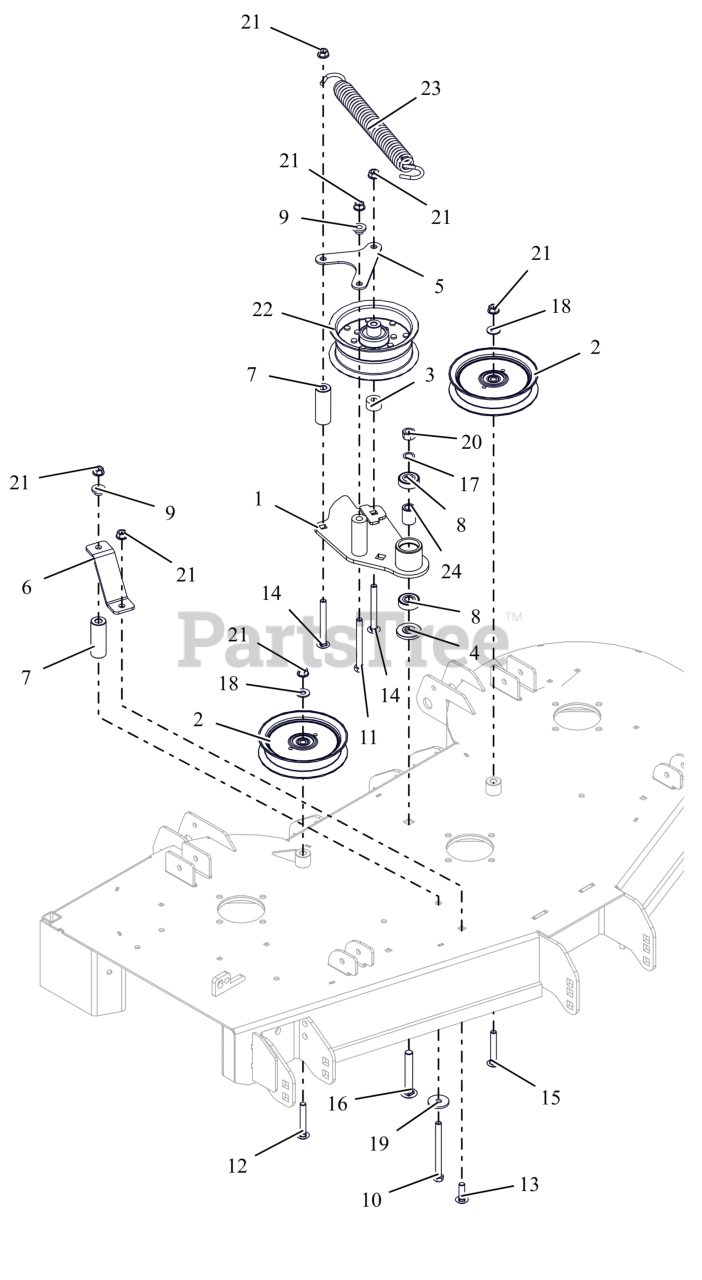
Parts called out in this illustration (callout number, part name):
1	WLDMT, IDLER ARM
2	IDLER, FLAT 5.00"
3	SPACER .390X1.000X.562
4	SPACER, IDLER ARM
5	BRKT, SUPPORT (BLACK)
6	BRKT, SPRG ANCHOR (BLACK)
7	SPCR, TUBE (BLACK)
8	BRG-BALL .500X1.38X.437
9	BSHG-FLG .385X.500X.875X.406
10	BLT, HEX 0.375-16X4.25 GR5 ZCC
11	BLT, HEX 0.375-16X3.75 GR5 ZCC
12	BLT,RHSN .38-16X2.50 G5 ZCC
13	BLT,RHSSN .38-16X1.25 G5 ZCC
14	BLT,RHSSN .38-16X3.50 G5 ZCC
15	BLT, RHSSN.38-16X2.50 G5 ZCC
16	BTL,RHSSN .500-13 X 3.25 G5 ZCC
17	WASHER, .500X.750X.020 THRUST
18	WSHR,FLT .375X.875X.083 ZCC
19	WSHR,FLT .406X1.375X.135 ZCC
20	NUT,LK-CTR .50-13 GA ZCC
21	NUT-LK-CTR-FLG .375-16 GF ZCC
22	PULLEY, FLAT 5.00X2.36X.375
23	SPRING, EXTENSION
24	SPACER .510 X .75 X 1.1485
